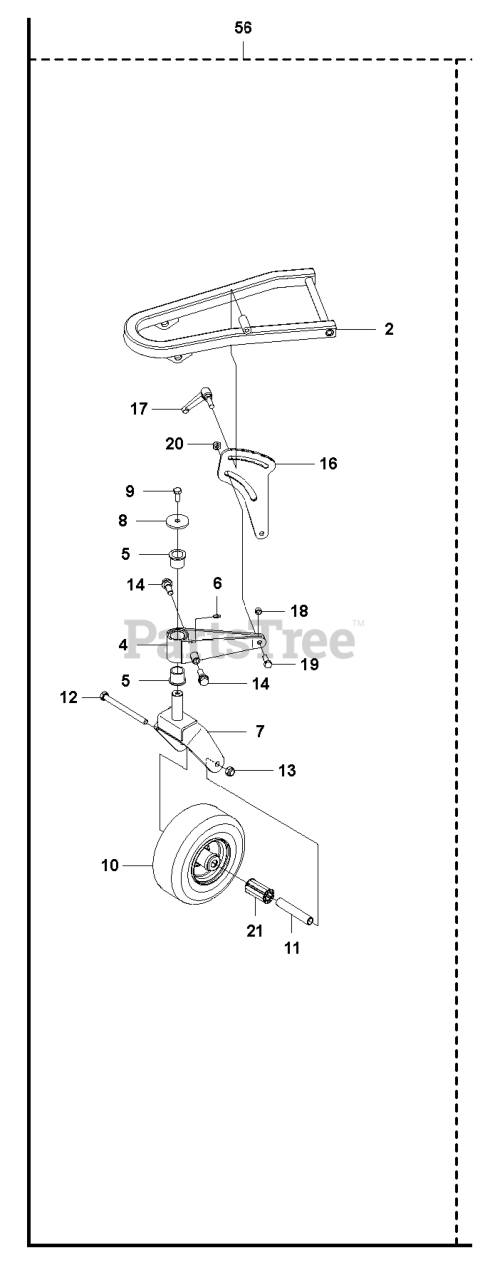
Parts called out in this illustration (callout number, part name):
2	SUPPORTING ARM RIGHT
4	PIVOT WHEEL SUPPORT RIGHT
5	BEARING BUSHING BRASS
6	GREASE NIPPLE
7	FORK PIVOT WHEEL
10	TIRE/WHEEL.CASTER.9X3.5-4.SMOO
16	SHEET HEIGHT ADJUSTER
17	TURNING KNOB M 10
18	SLEEVE PIVOT WHEEL SUPPORT
20	NUT
21	ROLLER BEARING
56	WHEEL SUSPENSION RIGHT
